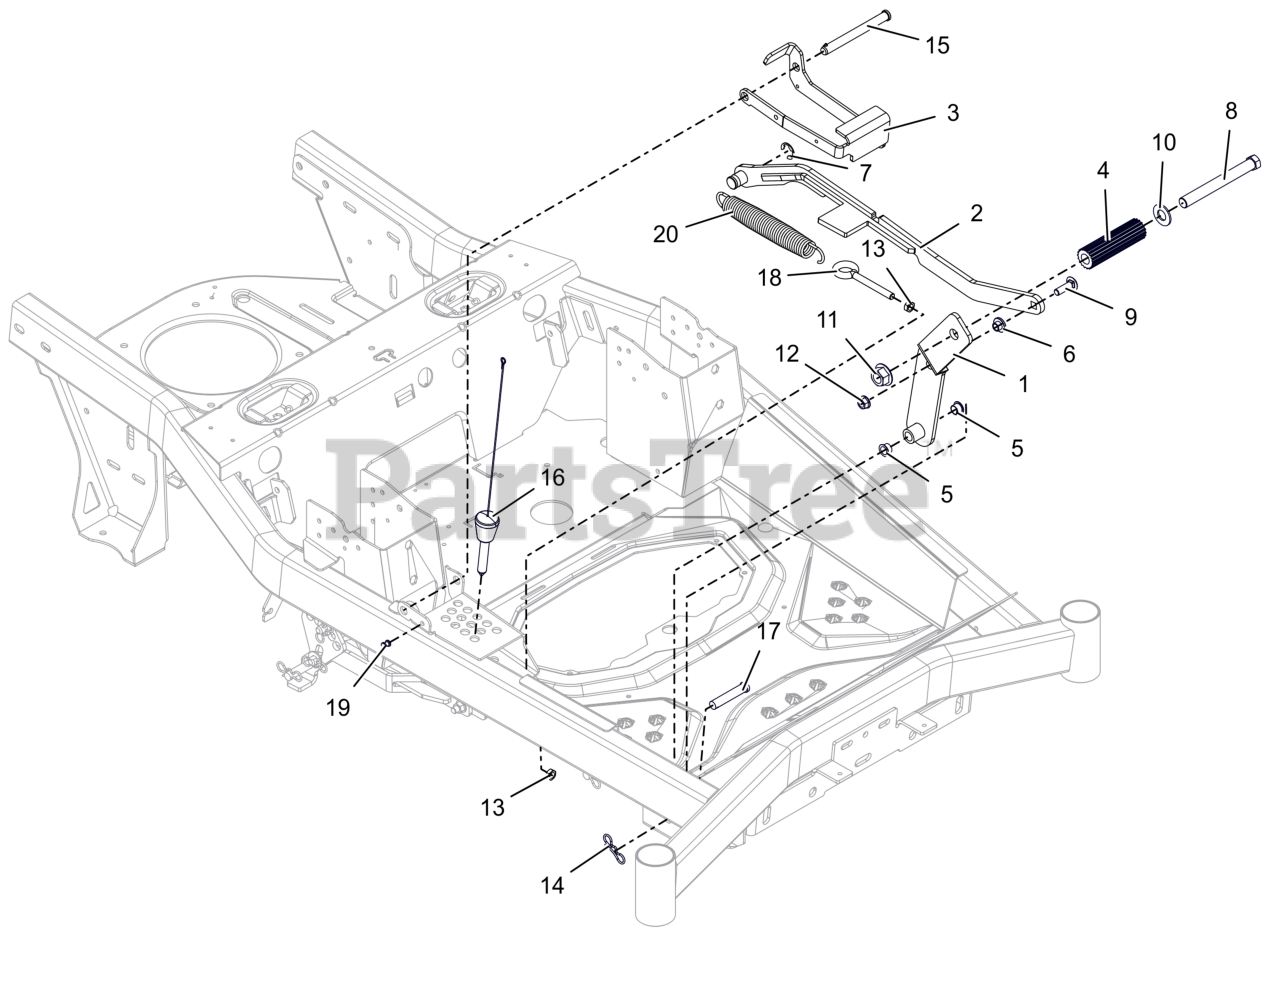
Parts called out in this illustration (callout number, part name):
1	WLDMT- FOOT PEDAL-ORG
2	LINK- DECK LIFT
3	WLDMT, TRANSPORT LOCK (ORANGE)
4	ROD, FOOT PEDAL (BLACK)
5	BUSHING, POLYLINER-.50 SPLIT
6	BSHG-FLG .385X.500X.875X.406
7	E-RING .750X.050
8	BLT, HEX .62-11X5.50 G5 FBP
9	BLT,RHSSN .38-16X1.25 G5 ZCC
10	WSHRFLT 5/8SAE CARBHARD FBP
11	NUT,FLG-TOP LK .625-11 FBP
12	NUT-LK-CTR-FLG .375-16 GF ZCC
13	NUT-JAM .375-16 G2 ZCC
14	PIN, BOWTIE .091X1.875 ZCC
15	PIN-SLIC .50X4.97X4.55 -ZCC
16	PIN- MAGNETIC .50X2.70
17	PIN-CLEV .494X2.50 BRIGHT ZINC
18	BOLT, EYE .38-16X4.50 .75 DIA
19	POST, & SCREW, PUSH LOCK .25 X .25
20	SPRG, EXTENSION
